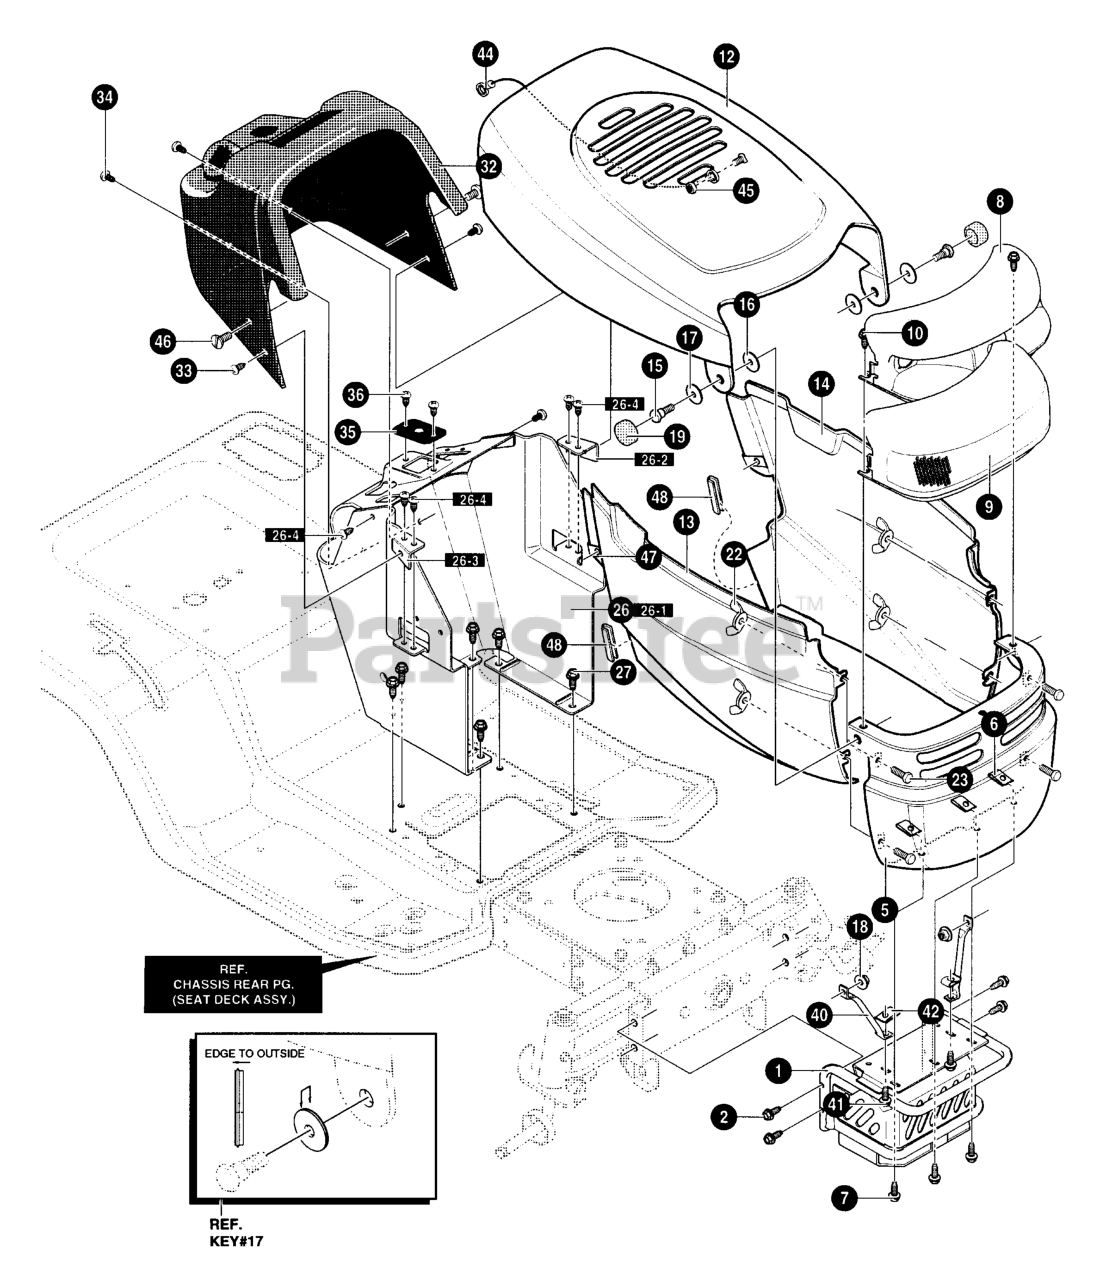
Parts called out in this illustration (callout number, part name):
1	BUMP/GRIL MNT
2	SCREW 5/16- 18X1.38
6	NUT, "J" TINNERMAN
7	SCREW 1/4-20X.63
8	REFLECTOR
10	SCREW, 1/4- 14X.50
12	ASSEMBLY, HOOD
13	PANEL, SIDE RH
14	PANEL, SIDE LH
16	WASHER, PLASTIC
17	PIVOT BASE
18	NUT, 3/8- 16
19	CAP, PIVOT
22	NUT, WING 1/4-20
23	SCREW 1/4- 20X1.25
26	CONSOLE ASSY
26-1	CONSOLE, DASH
26-2	BRACKET, LH
26-3	BRACKET, RH
26-4	SCREW, 10- 24X.5
27	SCREW 5/16- 18
33	SCREW 10- 24X.5
34	SCREW 10- 24X.5
35	STEERING BEARING
36	SCREW, 1/4- 14X.5
40	STRUT, GRILLE
41	SCREW 1/4-20X.63
42	SPEED NUT
44	LANYARD, HOOD
45	NUT, 1/4- 20
46	SCREW 1/4-20X.63
47	NUT, "J" TINNERMAN
48	TRIM
